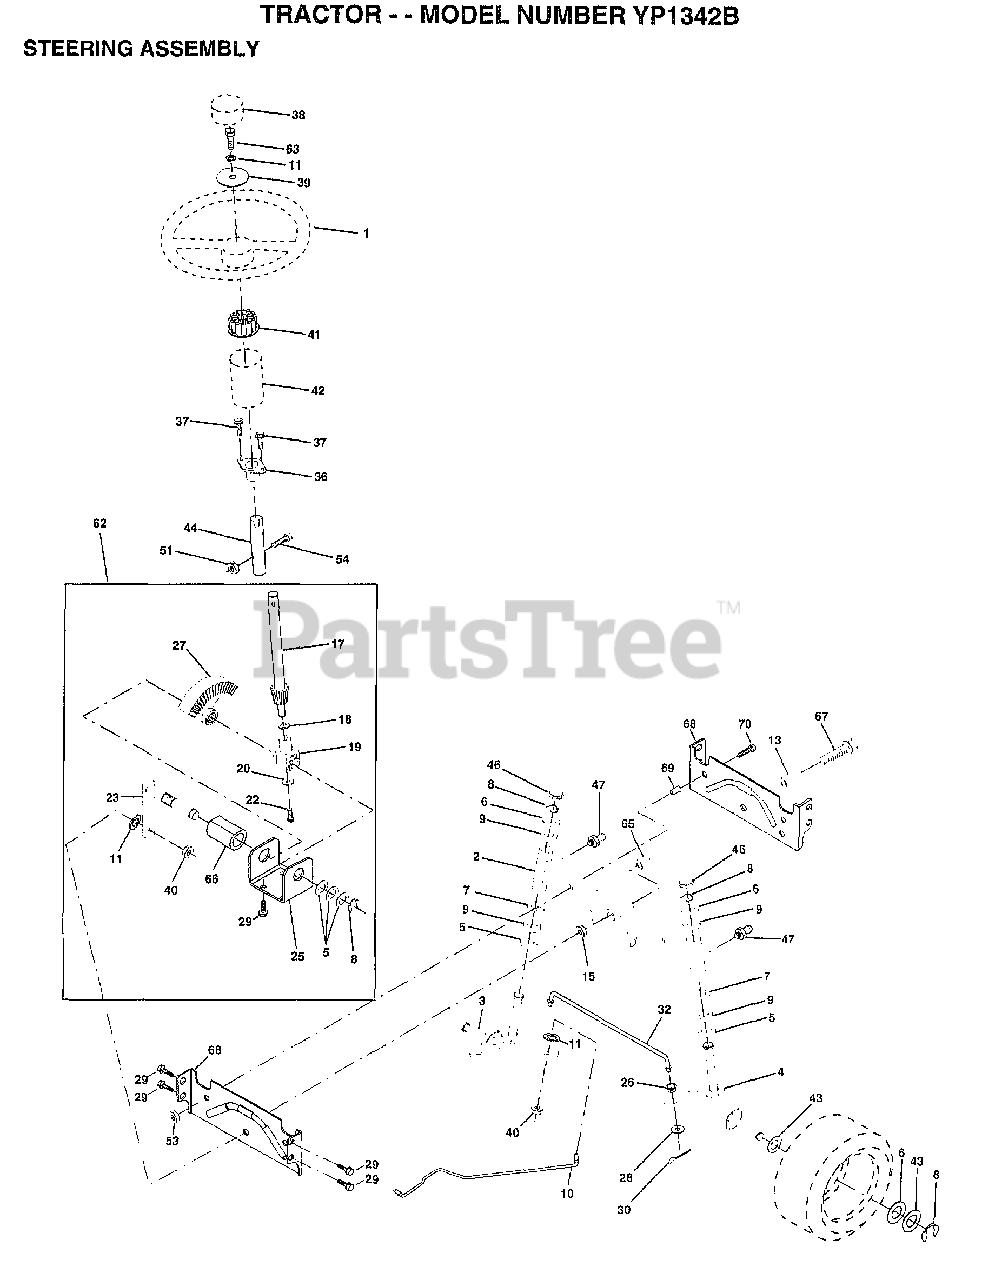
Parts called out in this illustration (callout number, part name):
1	WHEEL STR AYP BLK
2	AXLE ASM
3	SPINDLE.ASM.LH
4	"SPINDLE ASM,RH"
5	WASHER .T
6	WASHER
7	WASHER
8	RING
9	COL. SRTG. BEAR.
10	DRAGLINK-STAMPED
11	LOCKWASHER
13	BEARING AXLE
15	"NUT-LOC,FLANGE LT"
17	SHAFT ASM STEERIN
18	THRUST WASHER
19	SUPPORT.SHAFT
22	SCREW HEX SOC1/4-
25	BRKT-STEERING
26	BUSHING.DRAGLINK
27	GEAR SECTOR
28	WASHER
29	SCREW
30	COTTER PIN
32	TIE ROD
36	BUSHING.STEERING
37	"SCREW-TT,10-32 FL"
38	CAP STEER AYP
39	WASHER T
40	GRIPCO NUT
41	ADAPTER LT
42	BOOT.STEER.PL
43	WASHER
44	EXT SHAFT STEERIN
46	CAP
47	ZERK M
51	NUT
54	BOLT
62	KIT STEERING ASM
63	BOLT
65	SPACER AXLE
66	"BEARING-ARM,PITMA"
67	BOLT
68	BRACE AXLE
69	"SPACER BRCAE,AXLE"
70	BOLT.HEX.3/8-16X2
